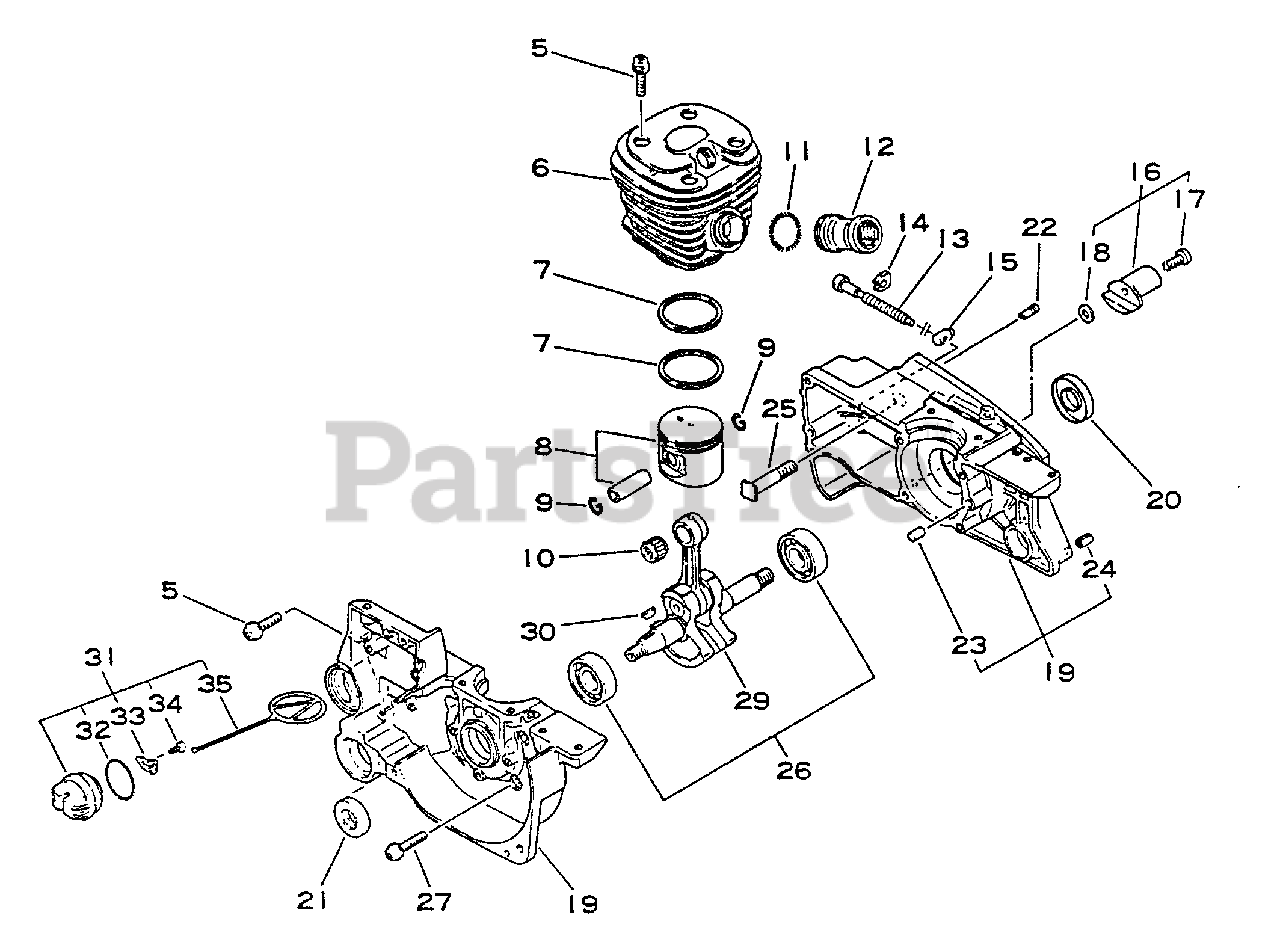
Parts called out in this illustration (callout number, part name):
5	SCREW - 5X20
6	CYLINDER
7	RING, PISTON
8	PISTON KIT
9	RING, RETAINING - 8
10	BEARING, NEEDLE
11	BAND
12	ADAPTOR, INTAKE
13	SCREW, TENSIONER
15	TENSIONER, CHAIN
16	CHAIN CATCHER KIT
17	SCREW - 5X20
19	CRANKCASE KIT
20	SEAL, OIL
21	SEAL, OIL
22	VENT, TANK
23	PIN - LOCATING
24	PIN - SPRING -- 5X10
25	STUD, GUIDE BAR
26	BEARING SET
27	SCREW - 5X30
29	CRANKSHAFT ASSY
31	CAP ASSY
33	RETAINER
34	SCREW - 3X8
35	CONNECTOR, CAP
36	CONNECTOR
